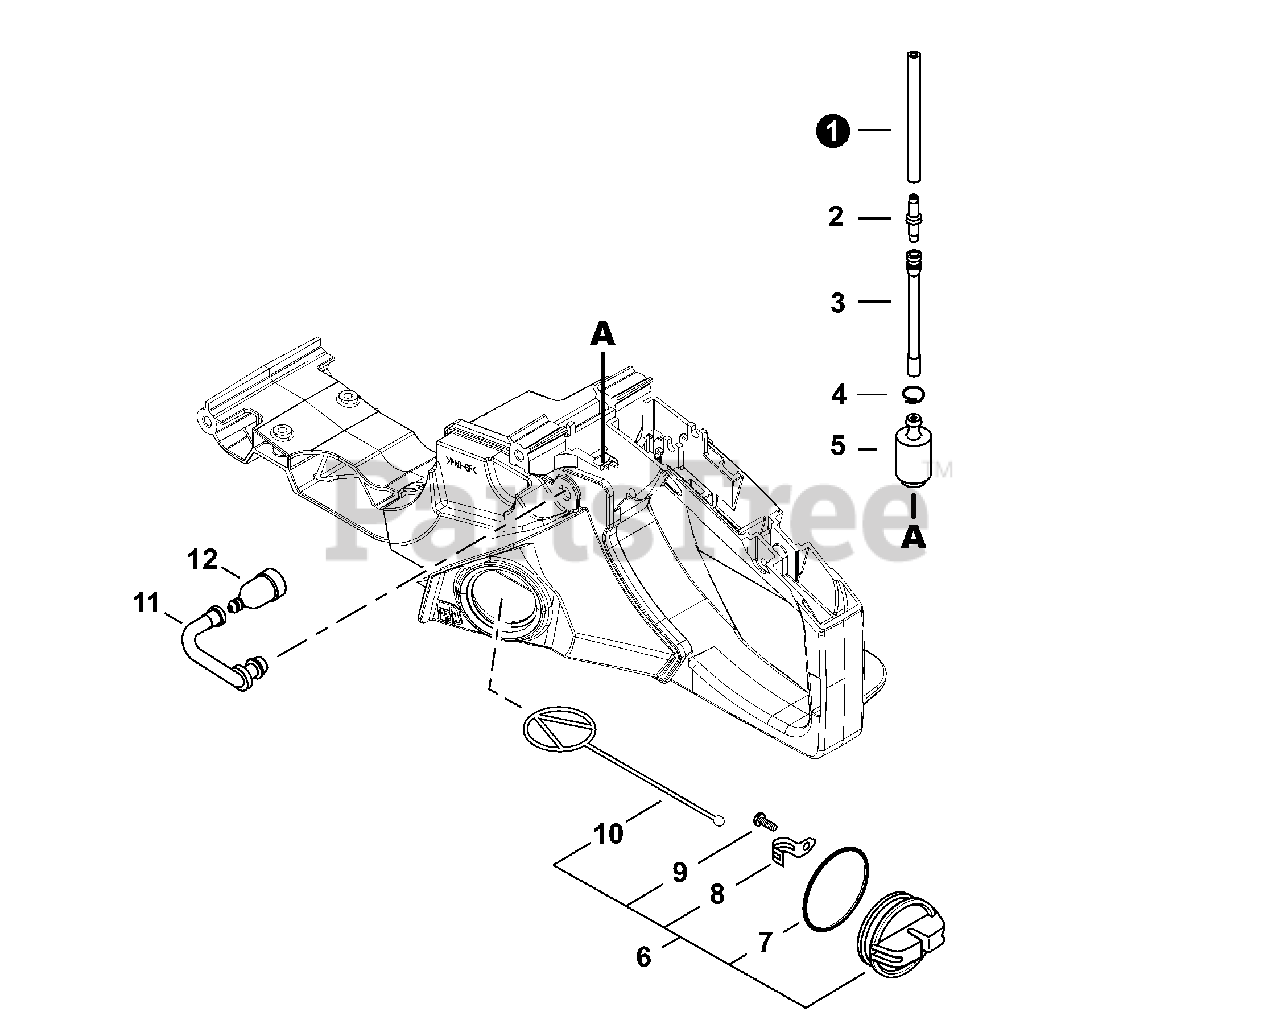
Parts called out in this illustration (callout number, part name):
1	PIPE, FUEL 3×6×75
2	CONNECTOR, PIPE
3	PIPE, FUEL
4	CLIP Ø6
5	FILTER, FUEL
6	CAP ASSY, FUEL
7	O-RING 29
8	RETAINER, CONNECTOR
9	SCREW, TAPPING 3×8
10	CONNECTOR, CAP L= 60 MM
11	PIPE, FUEL VENT
12	VENT ASSY
